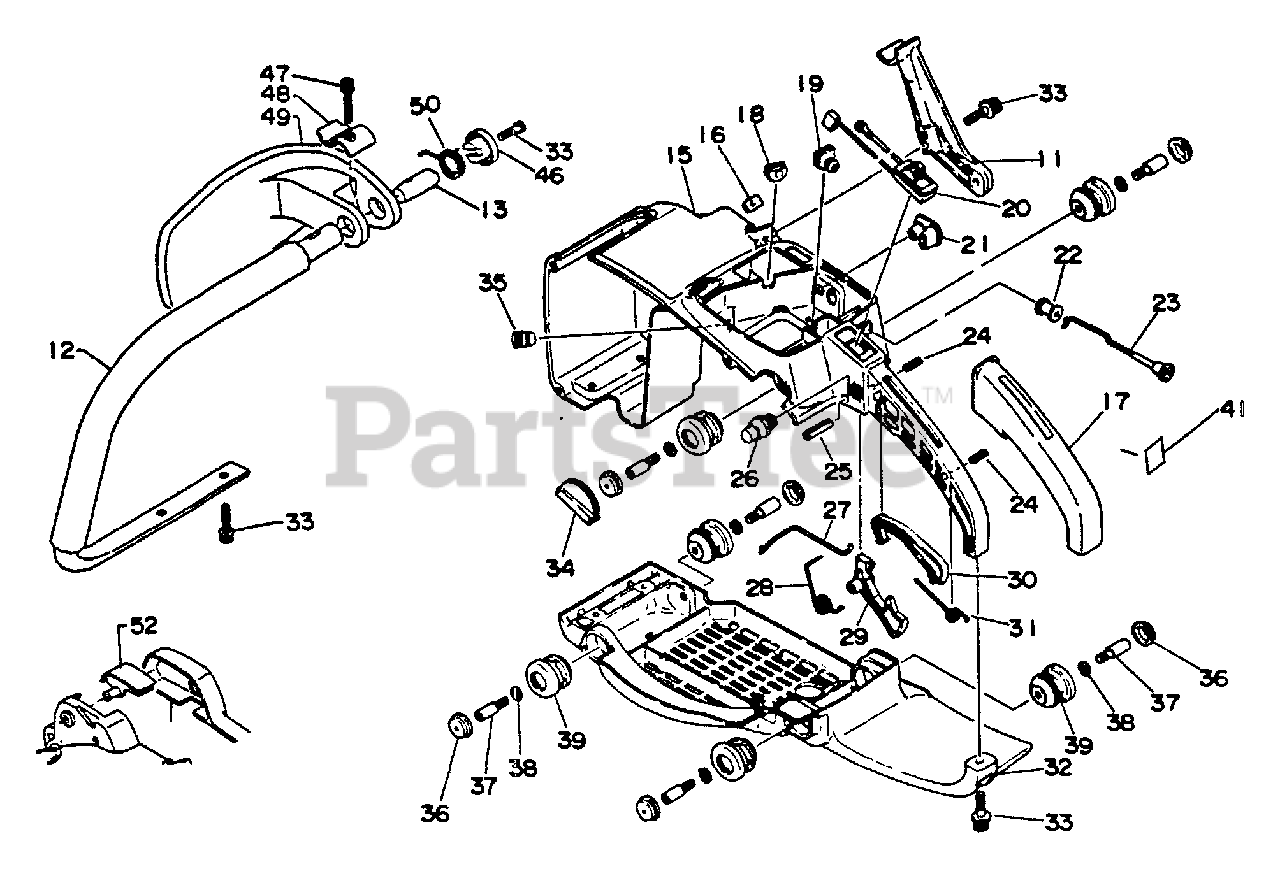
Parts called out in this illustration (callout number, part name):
11	BRACKET, HANDLE - UPPER
12	HANDLE, FRONT
15	HANDLE - REAR
17	GRIP, HANDLE
20	SWITCH, STOP
21	GROMMET
22	GROMMET, CHOKE
23	ROD, CHOKE
24	PIN, SPRING 4×13
25	PIN, SPRING 5×25
26	LATCH, THROTTLE
27	ROD, THROTTLE
28	SPRING, THROTTLE RETURN
29	THROTTLE
30	LOCKOUT, THROTTLE
31	SPRING, LOCKOUT RETURN
32	SUPPORT
33	BOLT 5×20
34	COVER, CUSHION
36	CAP, CUSHION
38	WASHER, SPRING 5
41	LABEL - CHOKE
46	RETAINER
47	BOLT M5×35
49	GUARD
52	COVER
